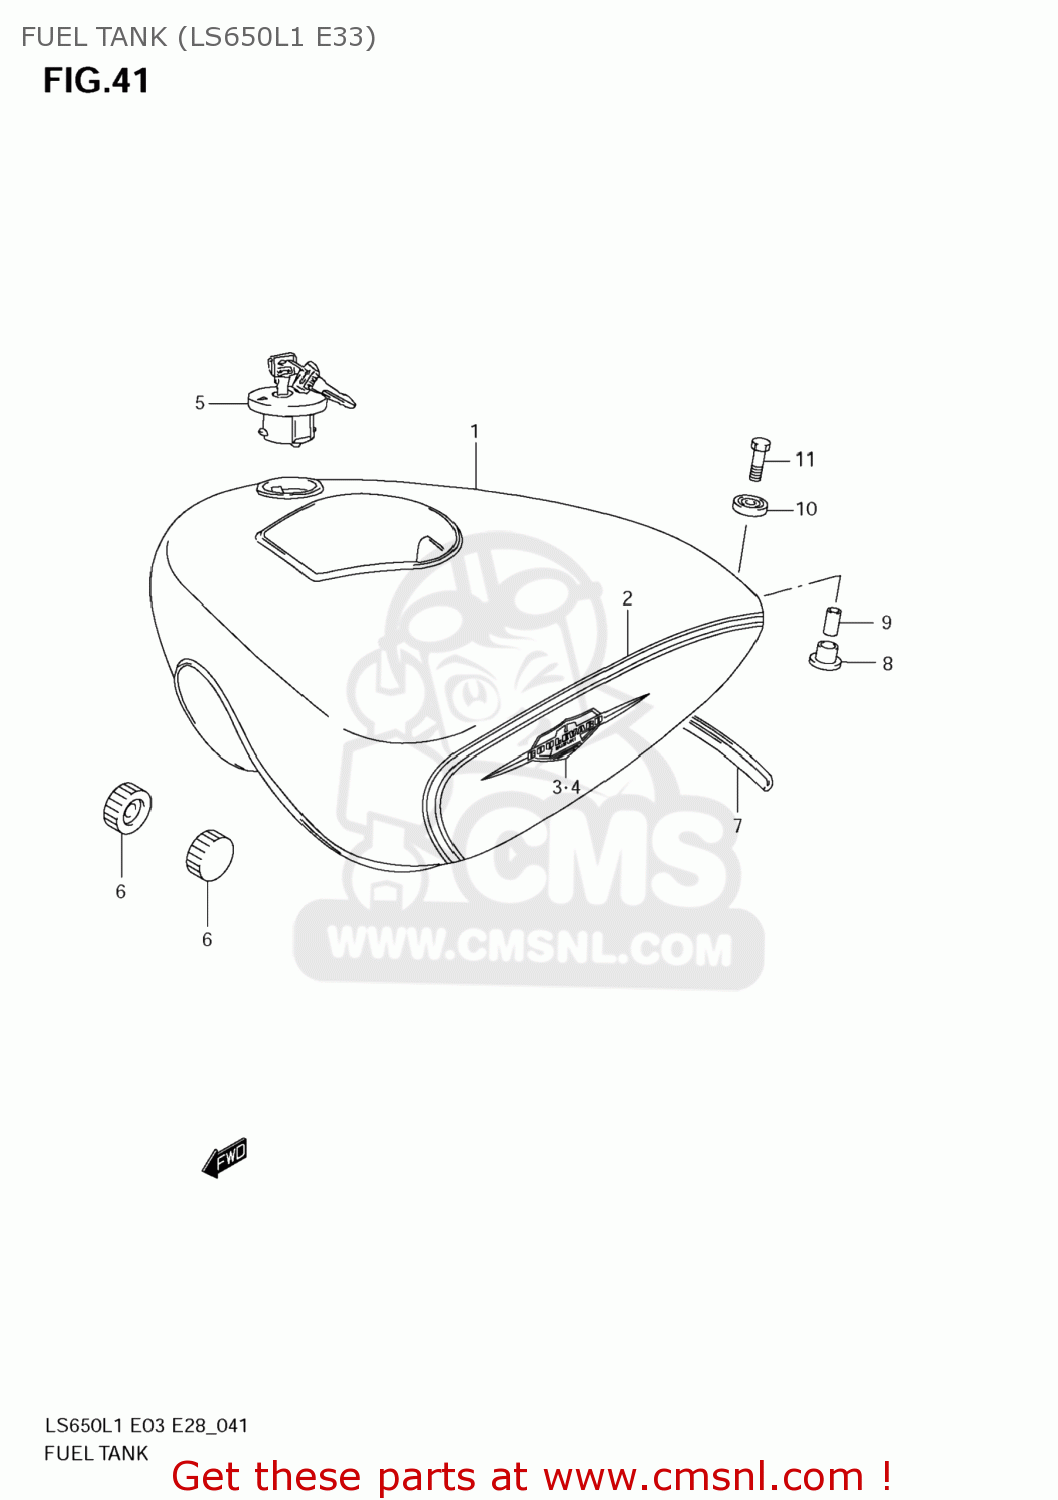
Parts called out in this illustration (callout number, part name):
1	TANK ASSY,FUEL
2	TAPE SET,FUEL TANK
3	EMBLEM,FUEL TANK,R
4	EMBLEM,FUEL TANK,L
5	CAP SET,FUEL TANK
6	CUSHION
7	MOLDING,FUEL TANK RR
8	CUSHION
9	SPACER(6.5X9X18)
10	CUSHION
11	BOLT
